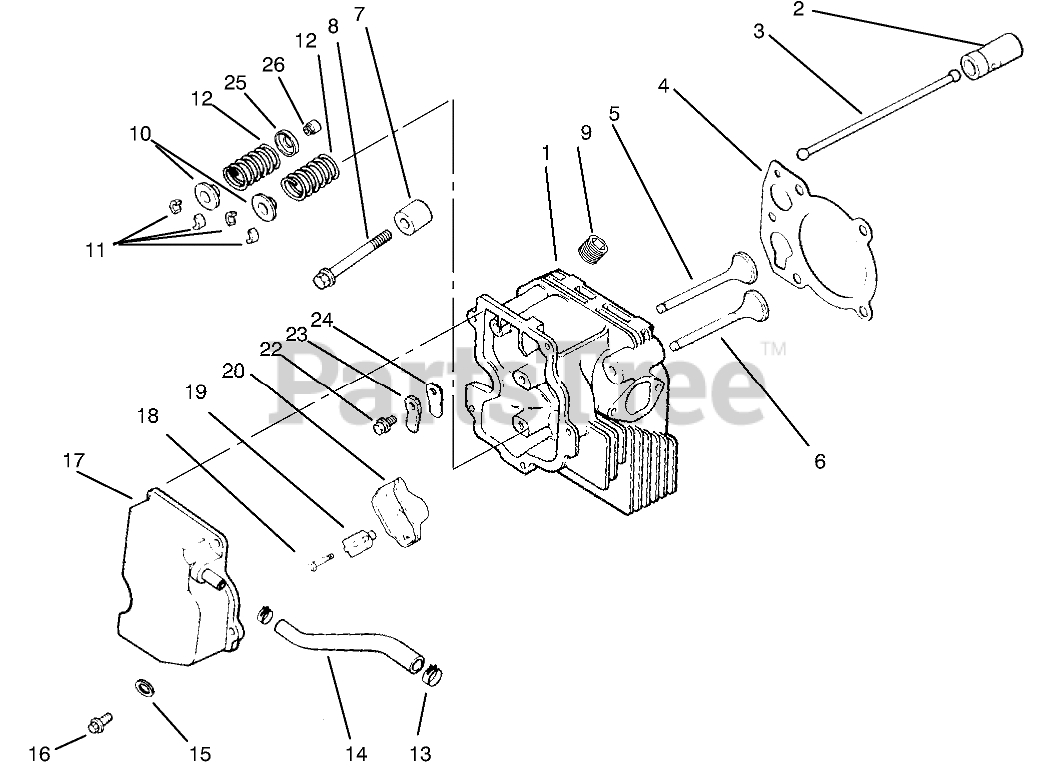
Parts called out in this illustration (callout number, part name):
1	Cylinder Head
2	Lifter-Valve
3	Rod-Push
4	Gasket-Cylinder Head
5	Valve-Intake STD
5	Valve-Intake .25
6	Valve-Exhaust STD
6	Valve-Exhaust .25
7	Spacer-Head Bolt
8	Screw M10x1.5x80
9	Plug
10	Cap-Spring, Valve
11	Retainer Kit
12	Spring-Valve
13	Clamp
14	Hose-Breather
15	Washer
16	Screw
17	Cover-Valve w/Nipple
18	Screw
19	Pivot-Rocker Arm
20	Arm-Rocker
22	Screw
23	Retainer-Reed
24	Reed-Breather
25	Retainer-Spring
26	Seal-Stem, Valve
